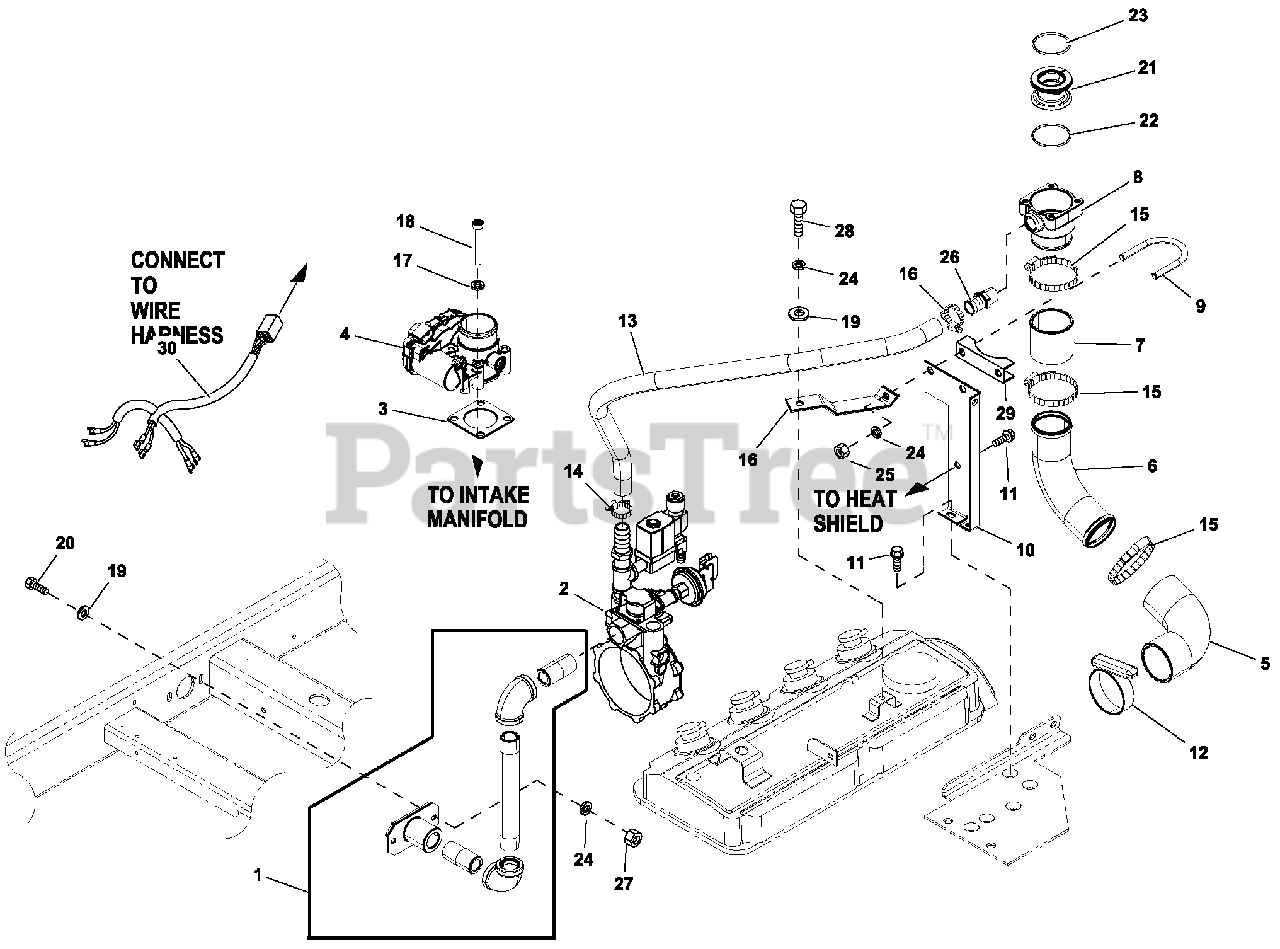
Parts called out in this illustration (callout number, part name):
1	BRACKET MUFFLER
2	BRACKET STIFFENER
3	UPPER EXHAUST PIPE ASM
4	MFLR8.5"X11.5"X19"2.5"IN/OUT
5	EXHAUST PIPE
6	DIFFUSER EXHAUST WELDMENT
7	EXHAUST PIPE
8	STRAP MUFFLER
9	BOLT U 3/8-16X2.62
10	SCREW THF M6-1 X 16 N WA Z/JS
11	WASHER FLAT 1/4-M6 ZINC
12	WASHER LOCK M6-1/4
13	SCREW HHC M6-1.0 X 35 G8.8 BLK
14	GASKET TURBO/EXHAUST 2.4L 36KW
15	WASHER LOCK M8 SS
16	SCREW HHC M8-1.25X 25 SS
17	WASHER LOCK 3/8
18	NUT HEX 3/8-16 STEEL
19	BOLT U 3/8-16 X 2.30 W/SADDLE
